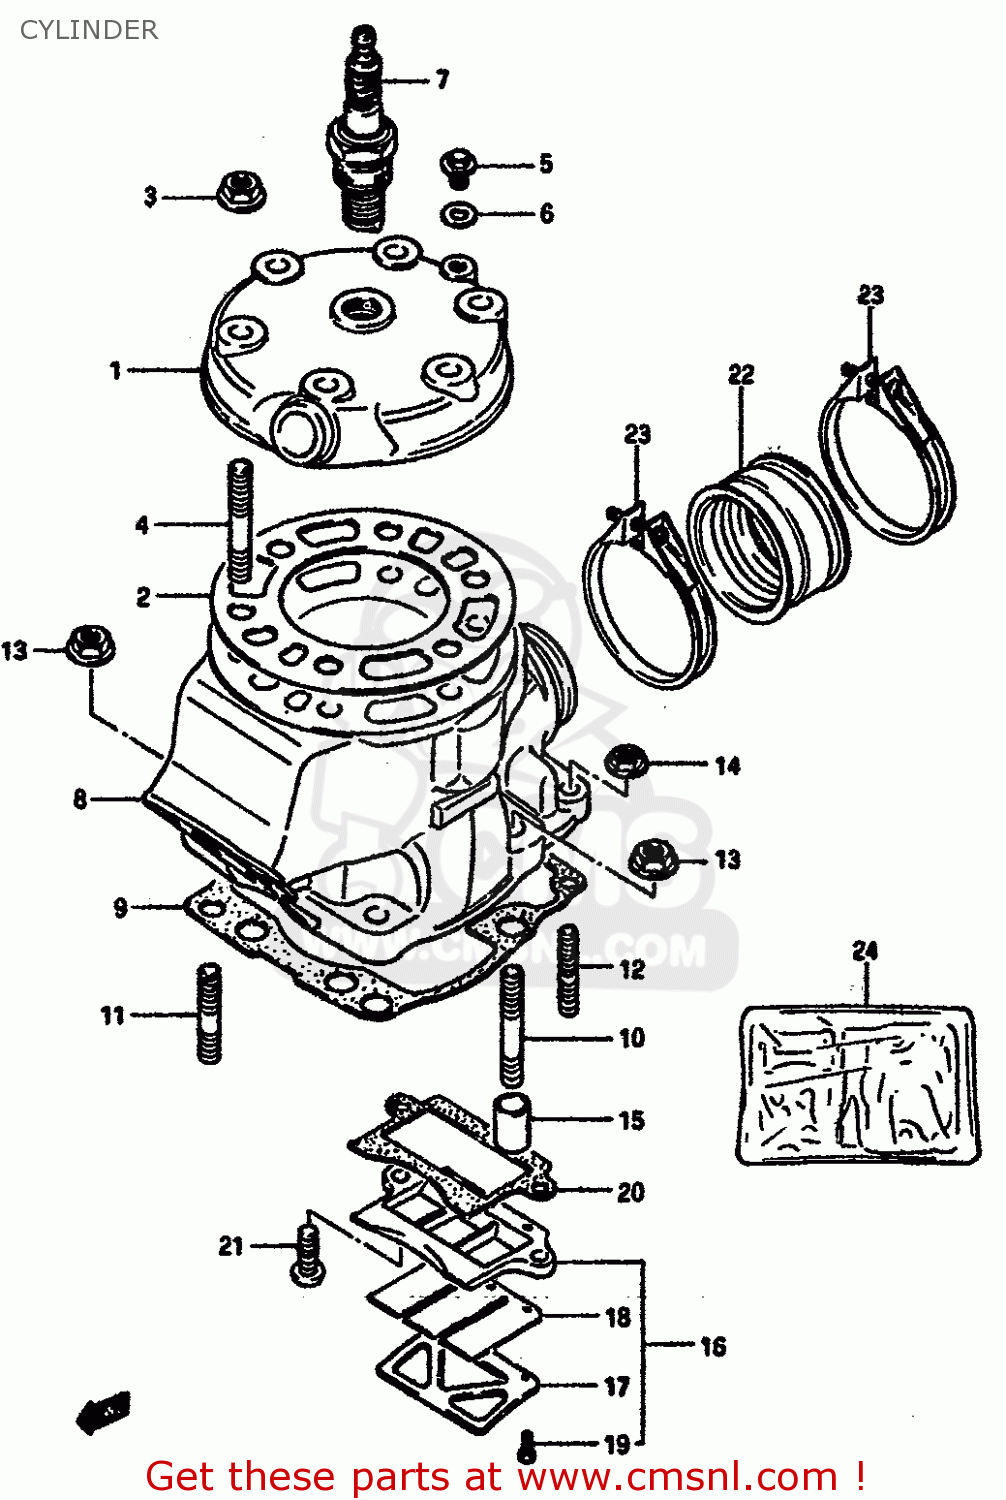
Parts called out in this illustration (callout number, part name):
1	HEAD,CYLINDER
2	GASKET,CYLINDER HEAD (MCA)
3	NUT 8MM
4	BOLT,STUD
5	UNION
6	GASKET(6.2X11X1).2 (NAS)
7	SPARK PLUG
8	CYLINDER
9	GASKET,CYLINDER (MCA)
10	STUD
11	STUD
12	STUD
13	NUT 8MM
14	NUT 6MM
15	PIN
16	VALVE ASSEMBLY,REED
17	STOPPER,REED VALVE
18	VALVE,REED
19	SCREW
20	GASKET,REED VALVE (MCA)
21	SCREW
22	PIPE,INTAKE
23	CLAMP
24	GASKET (MCA)
